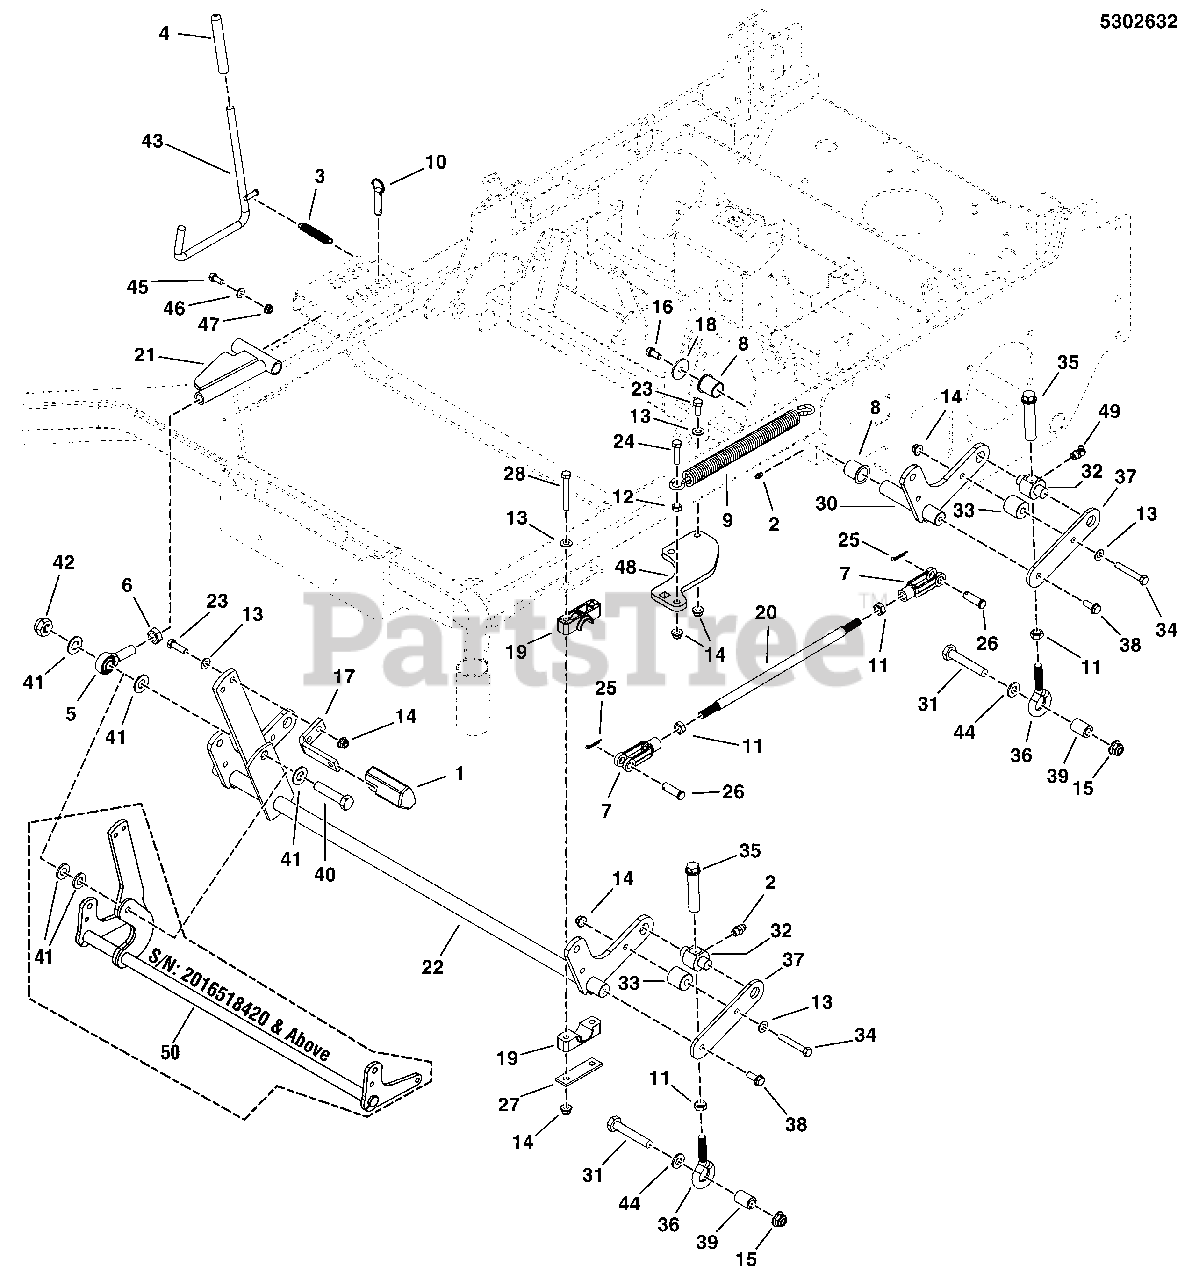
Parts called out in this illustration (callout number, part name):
1	PEDAL, Rubber
2	GREASE FITTING, 1/4-28 STRAIGHT
3	SPRING-EXT, .500 OD X 3.50 LG X .058 WR
4	GRIP, FOAM
5	BALL JOINT, 5/8-18, MALE
6	NUT, 5/8-18, HEX JAM
7	CLEVIS, 1/2-20, STEEL
8	BUSHING, 1.00 X 1.13 X 1.38, PLASTIC
9	SPRING-EXT, 1.393 ODX13.25LGX.218WR, BLK
10	PIN, HITCH, 1/2 X 2.00 OAL, YP
11	NUT, 1/2-20 HEX JAM
12	NUT, 3/8-16 HEX
13	WASHER, 3/8 SAE
14	NUT, 3/8-16 HEX NYLOCK FLANGE
15	NUT, Hex Flange, Nylock, 1/2-13
16	BOLT, 3/8-16 X 3/4, GD5, YZ WITH PATCH
17	PEDAL, FOOT - BLK
18	WASHER, .390 X 1.50 X .109, YZ
19	PIVOT BLOCK, PLASTIC
20	ROD, DECK LIFT, TWR
21	WELD, DECK ADJUSTER LINK - RED
22	WELD, DECK LIFT SHAFT - RED
23	BOLT, 3/8-16 X 1-1/4" GD5 CZ
24	BOLT, 3/8-16 X 1-3/4" GD5 CZ
25	PIN, COTTER, 1/8 X 3/4
26	PIN, CLEVIS, 1/2 X 1 1/2, YZP
27	PLATE, PIVOT BLOCK SUPPORT - BLK
28	BOLT, 3/8-16 X 2-3/4" GD5 CZ
30	WELD, DECK LIFT PIVOT, LH - BLK
31	BOLT, 1/2-13 X 2-3/4 GD5 CZ
32	PIVOT, DECK LIFT
33	SPACER, .39 X 1.25 X 1.25, CZ
34	BOLT, 3/8-16 X 2-1/2" GD5 CZ
35	ADJUSTER, HEIGHT
36	EYE BOLT, 1/2-20 X 4-1/4, 1 EYE, CZ
37	BRACKET, DECK LIFT, 72 - RED
38	BOLT,HEX FLG, SER GD8 3/8-16X1, PATCH
39	SPACER, .52 X .87 X 1.25, CZ
40	BOLT, 5/8-11 X 2-1/2 GD5, CZ
41	WASHER, 5/8 SAE
42	NUT,5/8-11 HEX NYLON LOCK
43	WELD, ROD DECK LIFT - BLK
44	WASHER, 1/2 GD9 YZ
45	BOLT, 5/16-18 X 3/4 GD5
46	WASHER, 5/16" SAE
47	NUT, 5/16-18 HEX NYLOCK FLANGE
48	PLATE, DECK LIFT ASSIST
49	GREASE FITTING, 1/4-28, 90 DEGREE
50	WELD, DECK LIFT, 200XT-72 - RED
